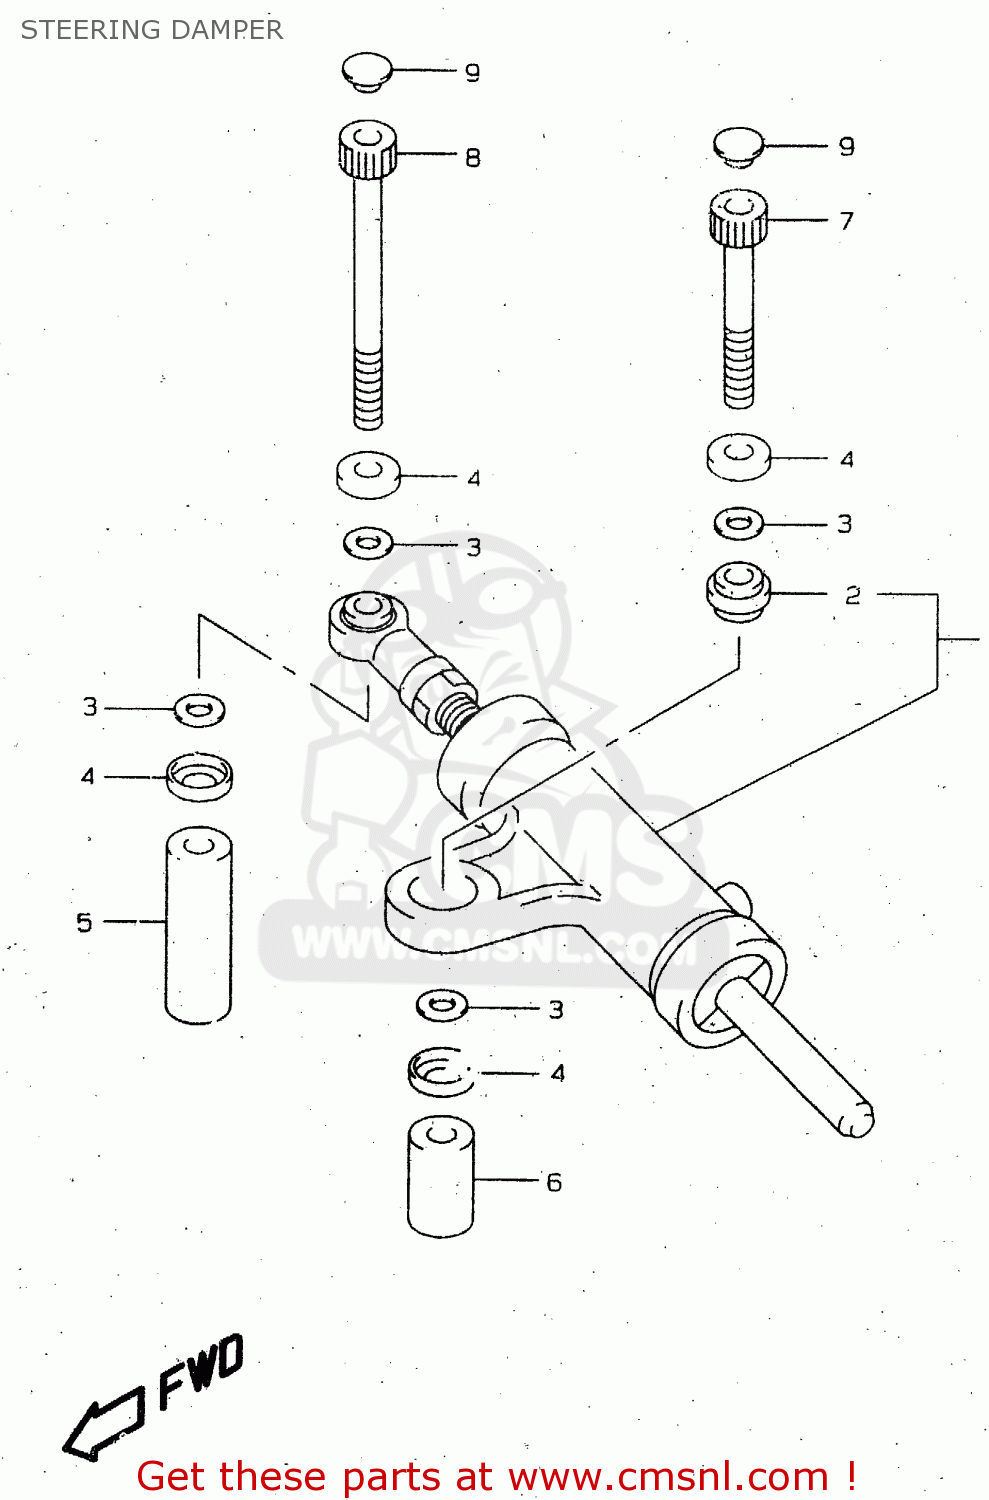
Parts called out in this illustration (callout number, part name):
1	DAMPER,STEERING
2	BEARING(8X17.5X11)
3	SHIM(8X12X0.8)
5	SPACER,STEERING DAMPER
6	SPACER,STEERING DAMPER
7	BOLT
8	BOLT
9	CAP(OD:11)
